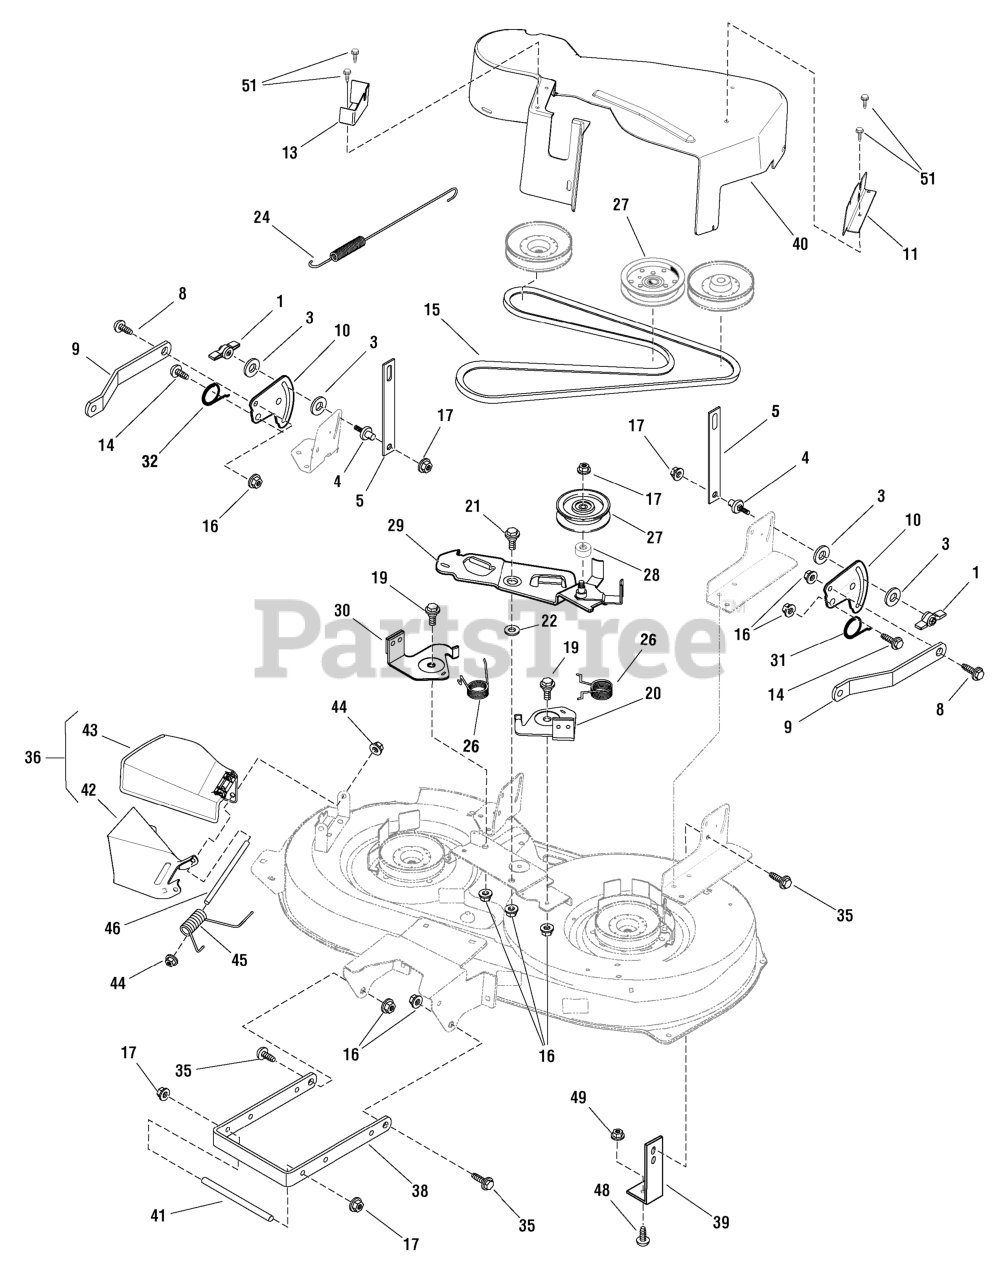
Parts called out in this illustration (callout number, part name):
1	KNOB (5/16-18 nut enclosed)
3	FRICTION PAD
4	PIN, Hanger
5	LINK, Lift (LT)
8	BOLT, Shoulder 3/8-16 x 1
9	BRACKET, Suspension
10	PLATE, Suspension
11	PLATE, Left Guard
13	PLATE, Right Guard
14	BOLT, Shoulder 3/8-16 x 1
15	BELT, V Mower Drive 38 in
16	NUT, Hex Flange 3/8-16
17	NUT Flange, 3/8-16
19	BOLT, Shoulder 3/8-16
20	BRAKE ASSEMBLY, Left
21	BOLT, Shoulder
22	WASHER, Flat
24	SPRING, Extension
26	SPRING, Torsion Brake
27	PULLEY, Idler, 4 in
28	SPACER, 1/2 in to 17 mm
29	ASSEMBLY, Idler Arm, 38 in
30	BRAKE ASSEMBLY, Right
31	SPRING, Left Torsion
32	SPRING, Right Torsion
35	CAPSCREW, 5/16-18
36	ASSEMBLY, Deflector
38	BRACKET, Suspension Front
39	BRACKET, Support
40	COVER, 38 in
41	ROD HANGER
42	SUPPORT, Deflector
43	DEFLECTOR, Chute
44	CAP, Push On
45	SPRING, Torsion
46	ROD, Deflector
48	BOLT, Shoulder 5/16-18 x 1
49	NUT, Hex Flange, 5/16-18
51	SCREW, Hex 1/4 x 1/2
